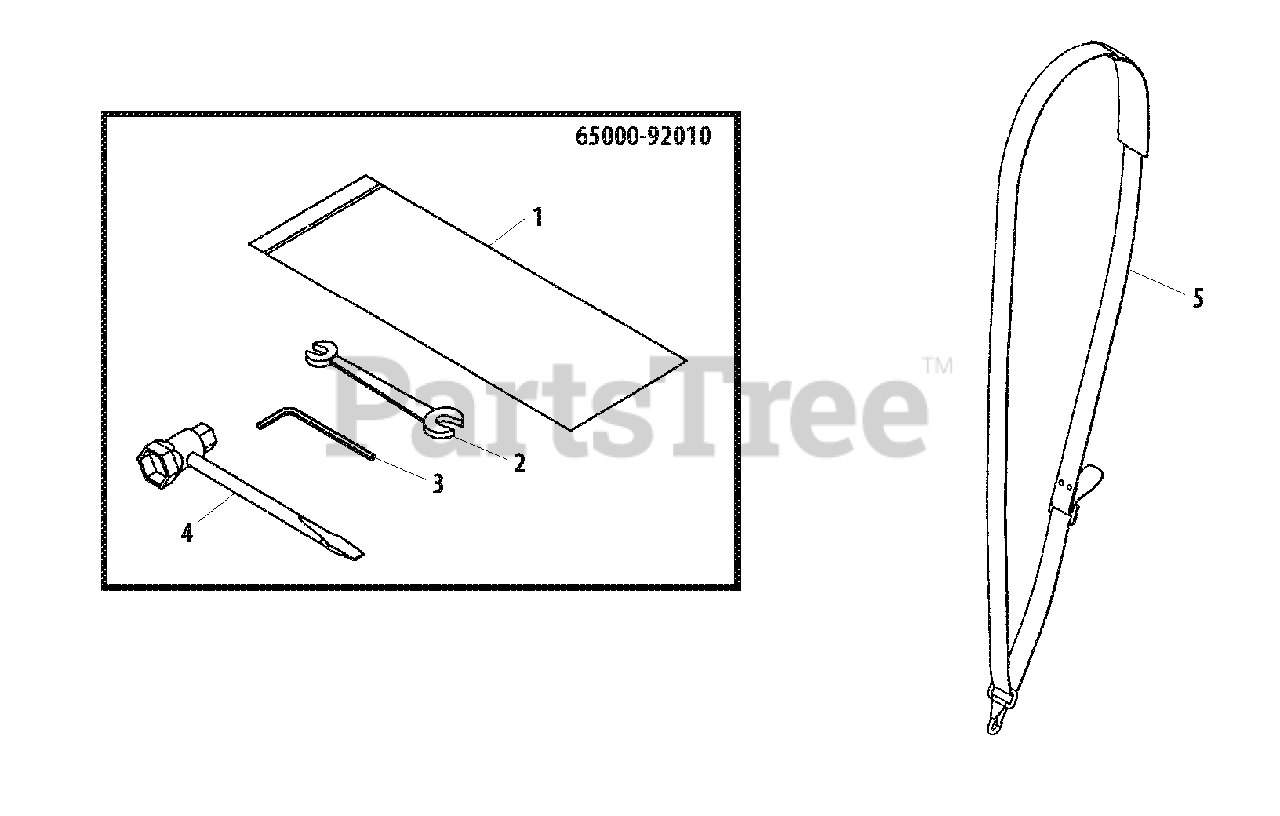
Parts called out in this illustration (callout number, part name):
1	BAG, TOOL
2	SPANNER - 8X10mm
3	HEX KEY - 4mm
4	T-WRENCH
5	STRAP ASSY
65000-92010	TOOL KIT
